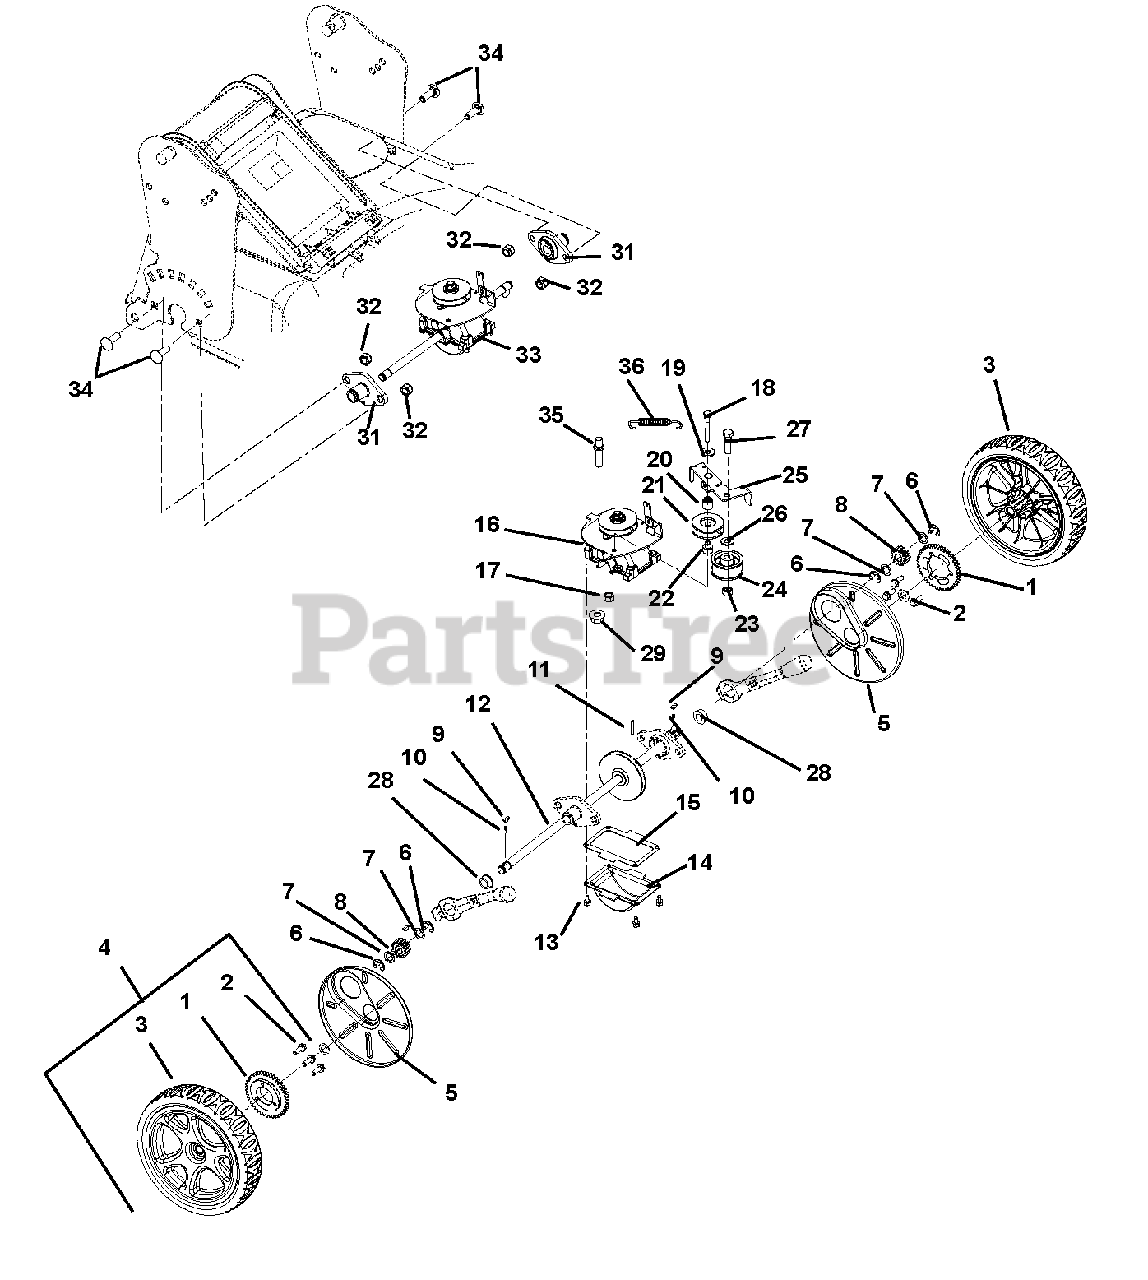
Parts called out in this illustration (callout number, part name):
1	Gear, Wheel (Order as part of kit 51111000. See item 4.)
2	Screw, Tapping .25-15 x .75 Hi-Lo Hex Washer Head (Order as part of kit 51111000. See item
3	Wheel (Order as part of kit 51111000. See item 4.)
4	Kit, Assembly, LM Rear Wheel (Contains items 1, 2 and 3)
5	Wheel Cover
6	Ring, Retaining External .500 x .042
7	Washer, .500 x .750 x .020 Thrust
8	Pinion, WBLM Drive
9	Key, Woodruff .125 x .50 x .20
10	Spring, .134 x .186 x .144 Compression
12	Shaft, Transmission Output
13	Screw, Tapping 10-24 x .375 Hex Washer Head
14	Sump, Gearbox
15	Gasket, Transmission
16	Kit, WBLM Transmission Housing
17	Nut, Locking Top Flange .25-20
18	Bolt, Hex .25-20 x 2.00 Grade 5
19	Washer, Flat Steel .328 x 1.0 x .094
20	Spacer, .390 x .75 x .189
21	Idler, 3L Front Side .38 x 1.875
22	Spacer, Idler Pulley
23	Nut, Locking Center .38-16
24	Idler, Flat 1.875 OD x .75 Wide
25	Arm, Transmission Idler
26	Washer, Flat Steel .406 x .812 x .065
27	Bolt, Hex .38-16 x 1.38 Grade 5
28	Bushing, Transmission Output Shaft
29	Nut, Locking Flange .250-20
30	Bracket, Transmission Control
31	Kit, Wheel Mount Hub Service
32	Nut, Locking Top Flange .31-18
33	Kit, Transmission Service
34	Bolt, Round Head Square Neck .31-18 x 1.00 Grade 5
35	Belt, Finger
36	Spring, Tension .051 x .60 x 2.25
